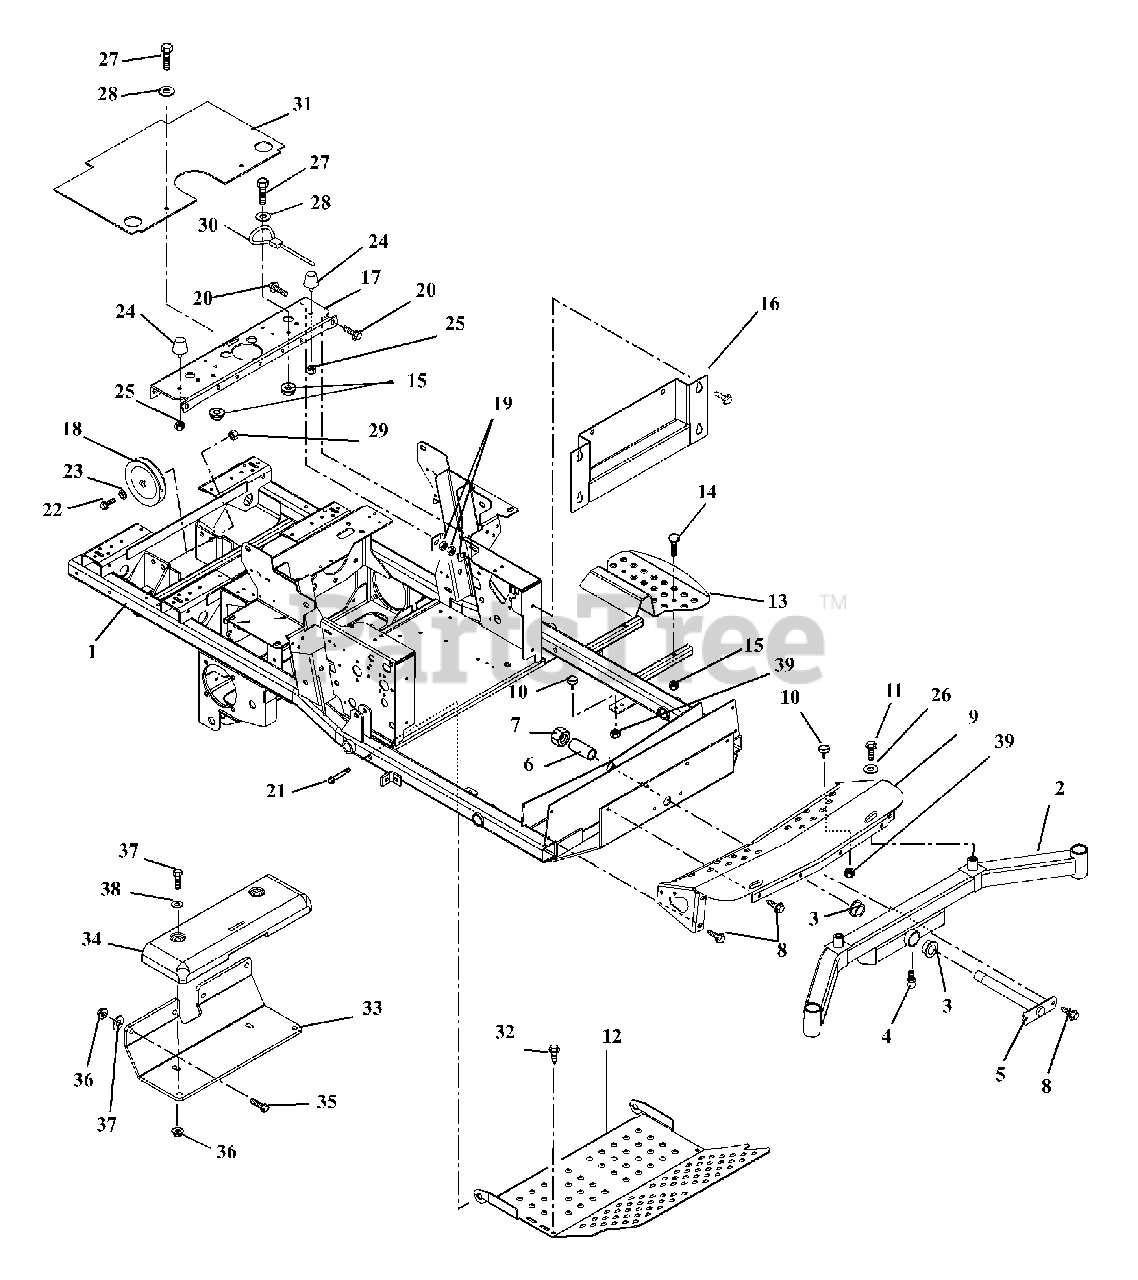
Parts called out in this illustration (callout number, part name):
1	WMT, FRAME-XDZ-LIQUID COOLED
2	WMT - FRONT AXLE
3	BSHG-FLG1.020X1.385X.75X1.75NY
4	FTG-LUBE .25-28X.256 YWZC
5	PIN - AXLE
6	SPACER 1.009 X 1.250 X 4.23
7	NUT-LK-NYL 1.0-14 YWZC
8	@SCR-TAP .38-16X.75 HWH TR YWZ
9	WMT - AXLE COVER
10	BUMPER, RUBBER
11	BLT-HEX .50-20X1.00 GR5 YWZC
12	PANEL - INSPECTION
13	STEP, INGRESS (BLACK)
14	@BLT-RDHDSQNK .31-18X1.75 G5YZ
15	@NUT-LK-TOP-FLG .31-18 YWZC
16	PLATE - KICK
17	CHANNEL, CROSS (BLACK)
18	PLY-V 6.0 X .500 ID DBL BRG.
19	NUT-RTNR .375-16X.37
20	BLT-SERHFWH .375-16X1.0 YWZC
21	@BLT-HEX .50-13X3.25 GR5 YWZC
22	@BLT-HEX .50-13X2.25 GR5 YWZC
23	WSHR-FL-STL .505X.880X.072 YWZ
24	BUMPER, RUBBER CONE,STUD MOUNT
25	@NUT-SPNLK-FLG .312-18 YWZC
26	WSHR-FLT .640X1.75X.250 YWZC
27	@BLT-HEX .31-18X1.00 GR5 YWZC
28	WSHR-FL-STL .344X1.125X.135
29	@NUT-LK-TOP-FLG .50-13 YWZC
30	CABLE, SEAT PROP.
31	GUARD - GRASS
32	@SCR-TAP .38-16X1.00 HWH TR YZ
33	BRACKET - WEIGHT - 252
34	WEIGHT, CAST IRON
35	@BLT-HEX .50-13X1.00 GR5 YWZC
36	@NUT-LK-TOP-FLG .50-13 YWZC
37	@BLT-HEX .50-13X4.50 GR5 YWZC
38	@WSHR-FL-STL.531X1.06X.095YWZC
39	@NUT-SPNLK-FLG .312-18 YWZC
